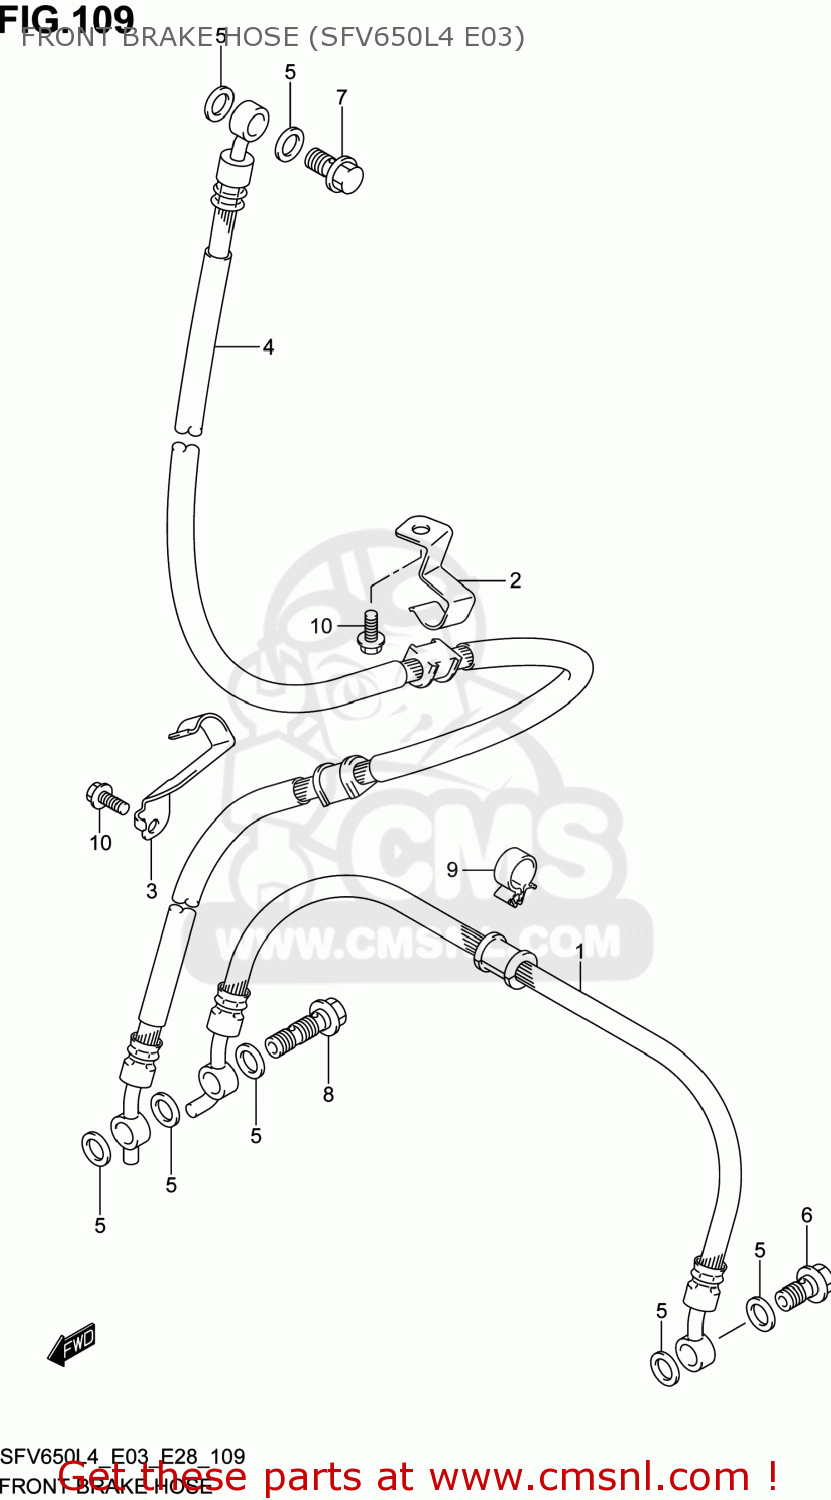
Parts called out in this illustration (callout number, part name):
1	HOSE,FR BRAKE NO.2
2	CLAMP,FR BRAKE HOSE NO.1
3	CLAMP,FR BRAKE HOSE NO.2
4	HOSE,FR BRAKE NO.1
5	WASHER(10X15X1.5)
6	BOLT UNION
7	BOLT UNION
8	BOLT UNION
9	CLAMP
10	BOLT
